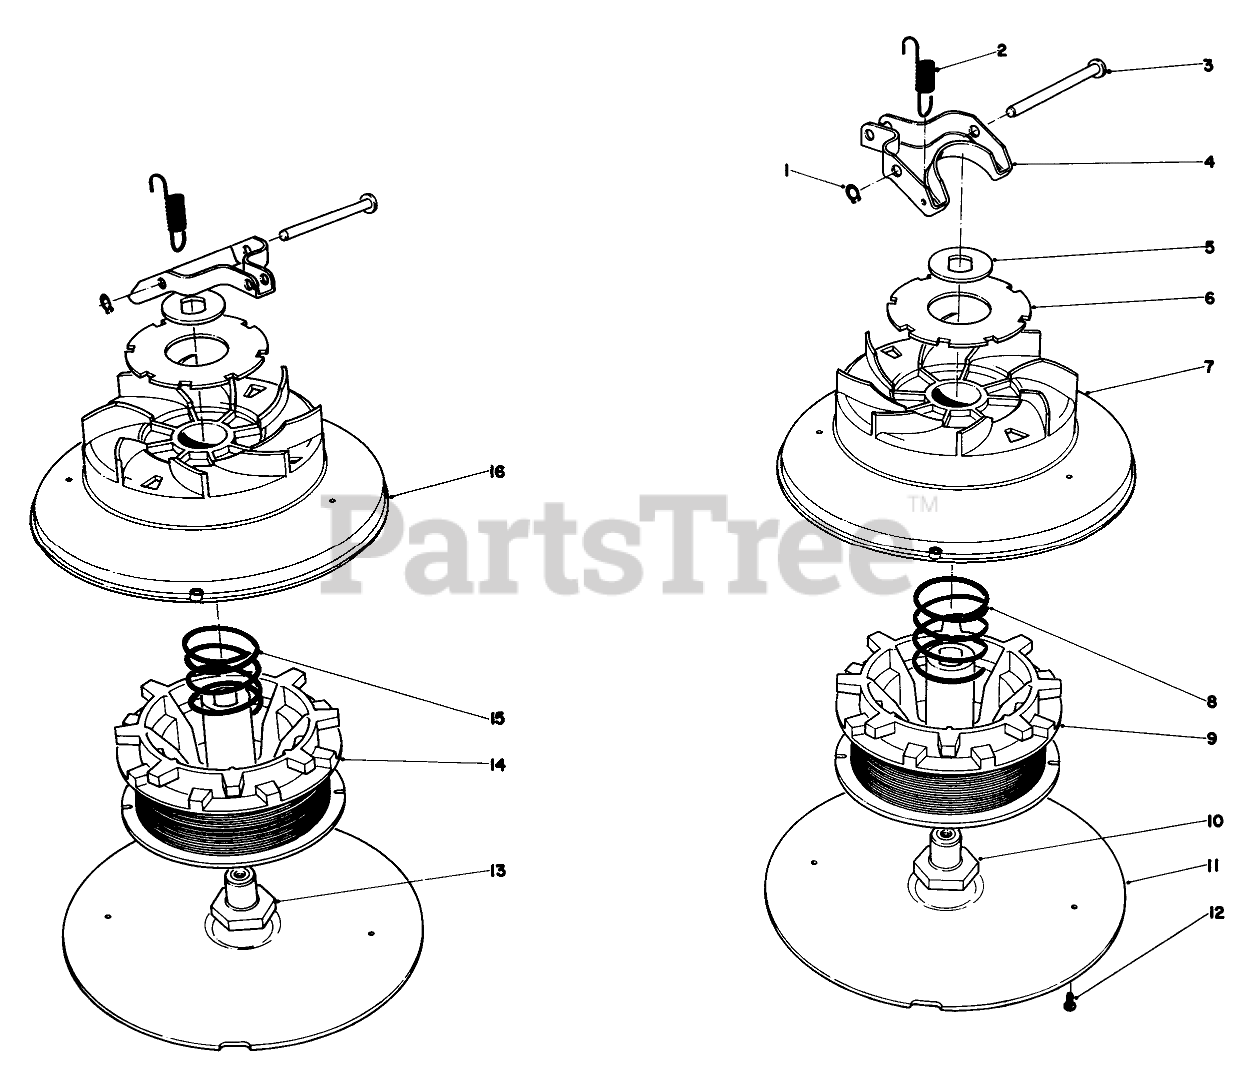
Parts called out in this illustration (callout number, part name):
1	Retaining Ring
2	Spring-Fork
3	Pivot Pin
4	Indexing Fork
5	WASHER
7	Drum L.H. (Incl. Ref. #6)
8	COMP SPRING
9	Spool Assy. L.H.
10	NUT LH
11	DRUM COVER
12	Screw
13	NUT RH
14	Spool Assy. R.H.
15	Spring R.H.
16	Drum R.H. (Incl. Ref. #6)
